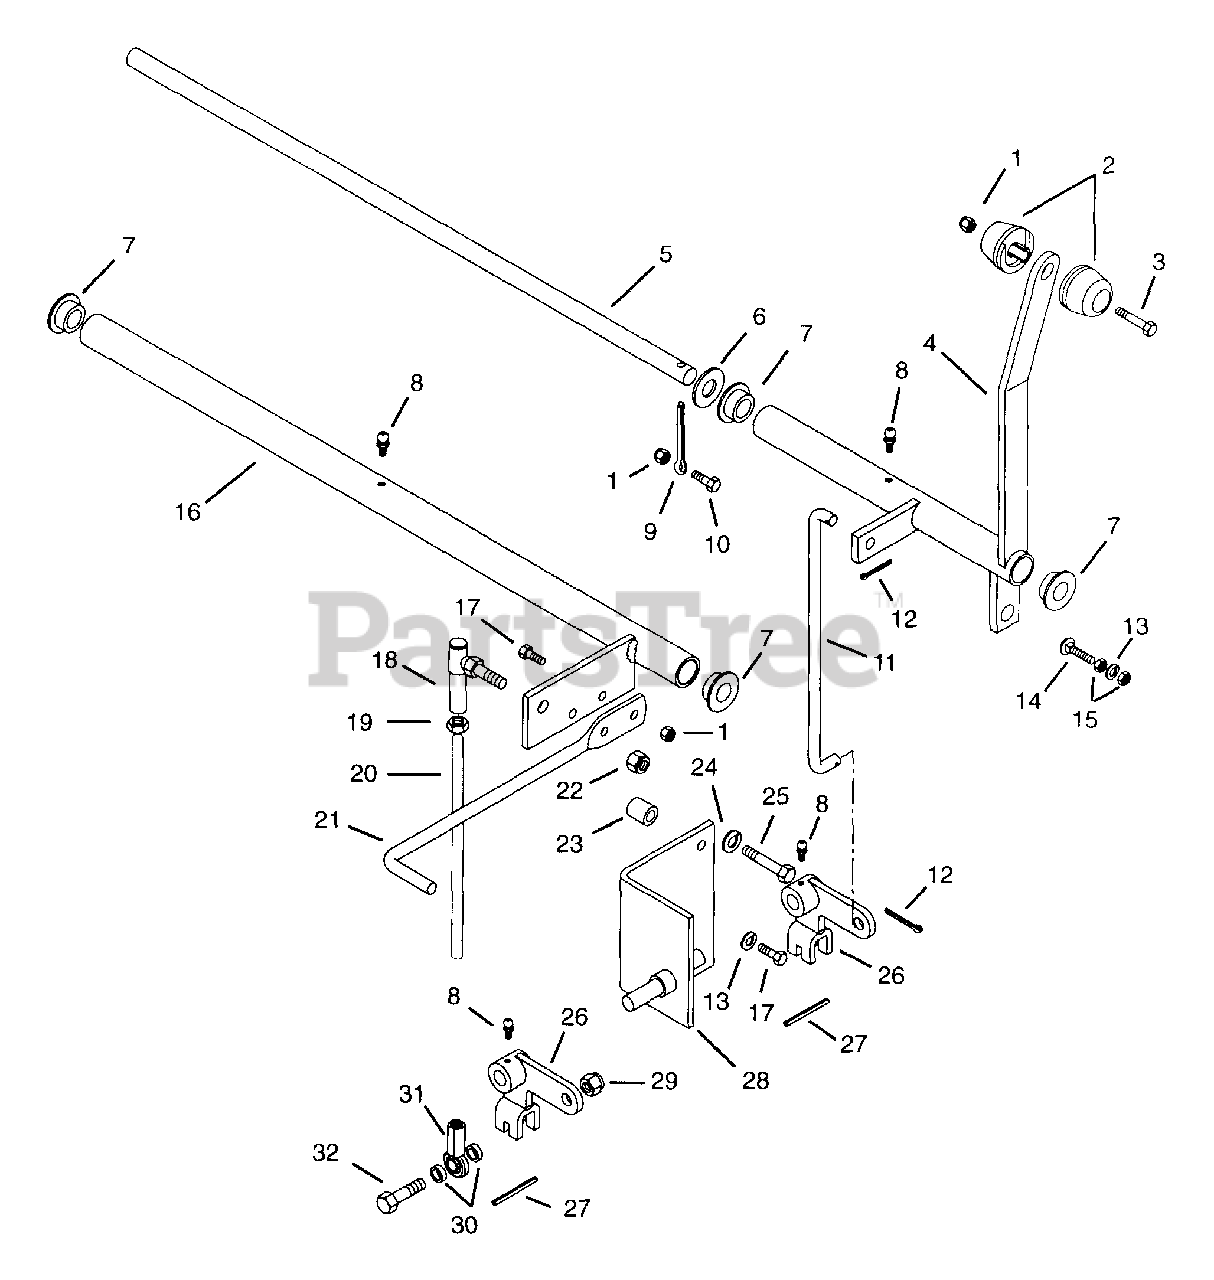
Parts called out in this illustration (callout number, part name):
1	Nut-Locking-Nylon .250-20 Grade 2
2	Knob, Control
3	Bolt-Hex .25-20 x 1.50 Grade 5
4	Control, Hi-Lo
5	Shaft, Control
6	Washer-Flat-Steel .531 x 1.062 x .095
7	Bushing-Flange .515 x .750 x .745 x 1.00
8	Fitting-Lube .25-28 x .256
9	Pin-Cotter .250 x 2.00
10	Bolt-Hex .25-20 x .875
11	Rod, Hi-Lo
12	Pin-Cotter .09 x .75
13	Washer-Lock .250 Reg.
14	Screw-Machine .25-20 x 1.25
15	Nut-Hex .250-20 Grade 2
16	Weldment, Differential Lock Control
17	Bolt-Hex .25-20 x .75 Grade 5
18	Joint, Steering Ball
19	Nut-Hex .375-24 Grade 2
20	Rod, Lock Control
21	Bar, Foot
22	Nut-Locking-Nylon .375-24 Grade 2
23	Bushing-Sleeve .407 x .625 x .750
24	Washer-Lock .313 x .078
25	Bolt-Hex .31-18 x 2.00 Grade 5
26	Lever, Hi-Lo
27	Pin-Roll .250 x 1.000
28	Bracket, Shift
29	Nut-Locking-Nylon .375-16 Grade 2
30	Bushing-Flange .383 x .50 x .165
31	Rod End, Spherical Bearing
32	Bolt-Hex .38-16 x 1.50 Grade 5
